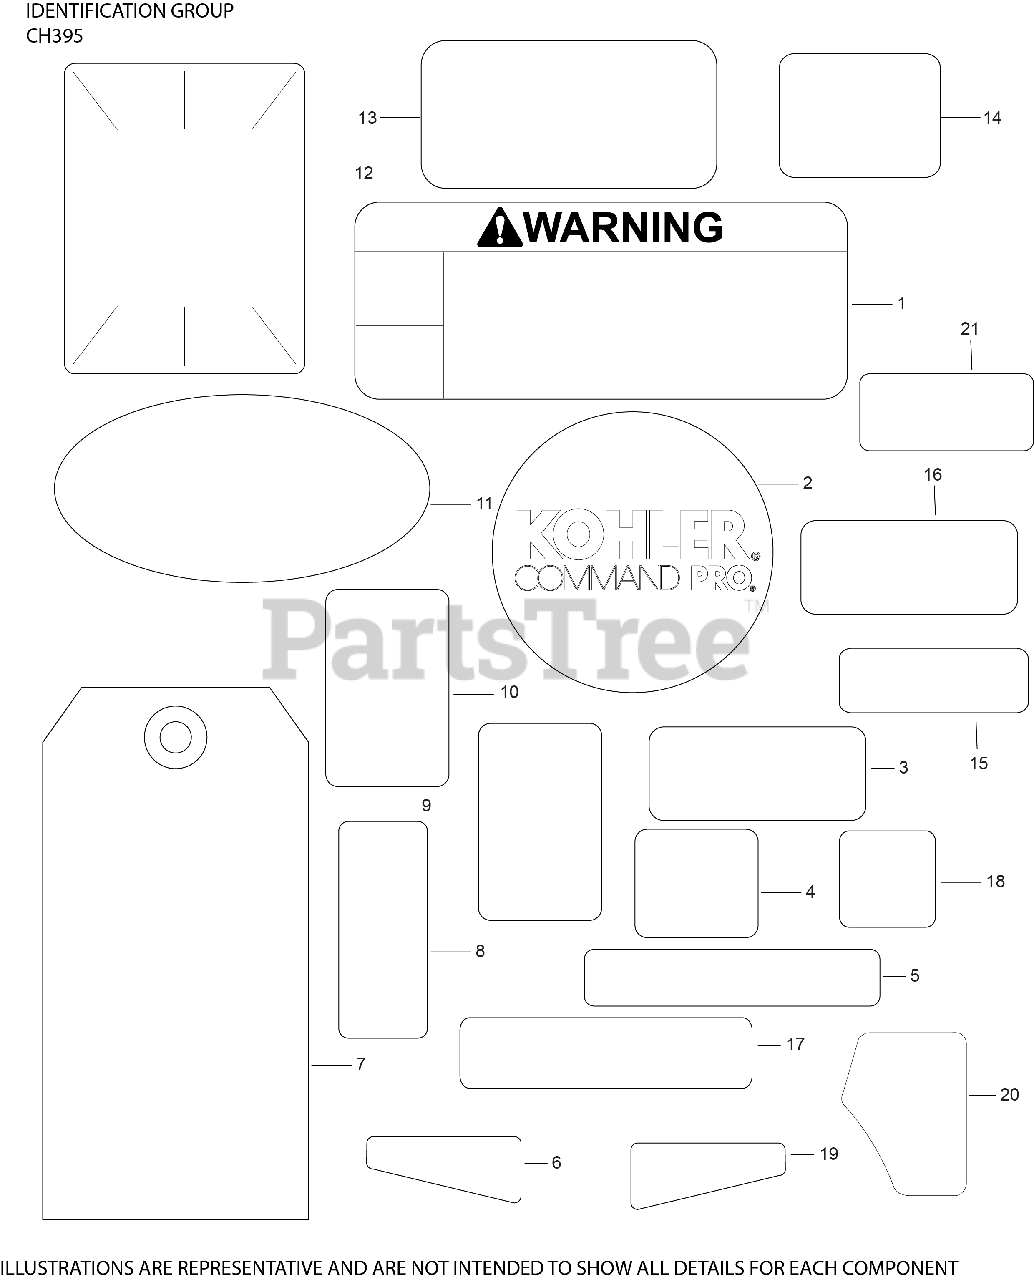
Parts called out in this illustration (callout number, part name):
1	DECAL, WARNING
2	LABEL, RECOIL 75MM
3	LABEL, CANADIAN COMPLIANCE
4	DECAL, BASE ARROW
5	DECAL, THROTTLE
6	DECAL, 9.5 HP/277cc/CH395
8	DECAL, FUEL/CHOKE - ON/OFF
9	DECAL, SUN
10	DECAL, SNOW FLAKE
11	DECAL, QUAD CLEAN SILVER
12	LABEL, CLEAR LAMINATION
13	LABEL, MAINTENANCE (CKY)
15	DECAL, ENGINE AND FUEL SHUT OFF
16	DECAL, ETHANOL WARNING
